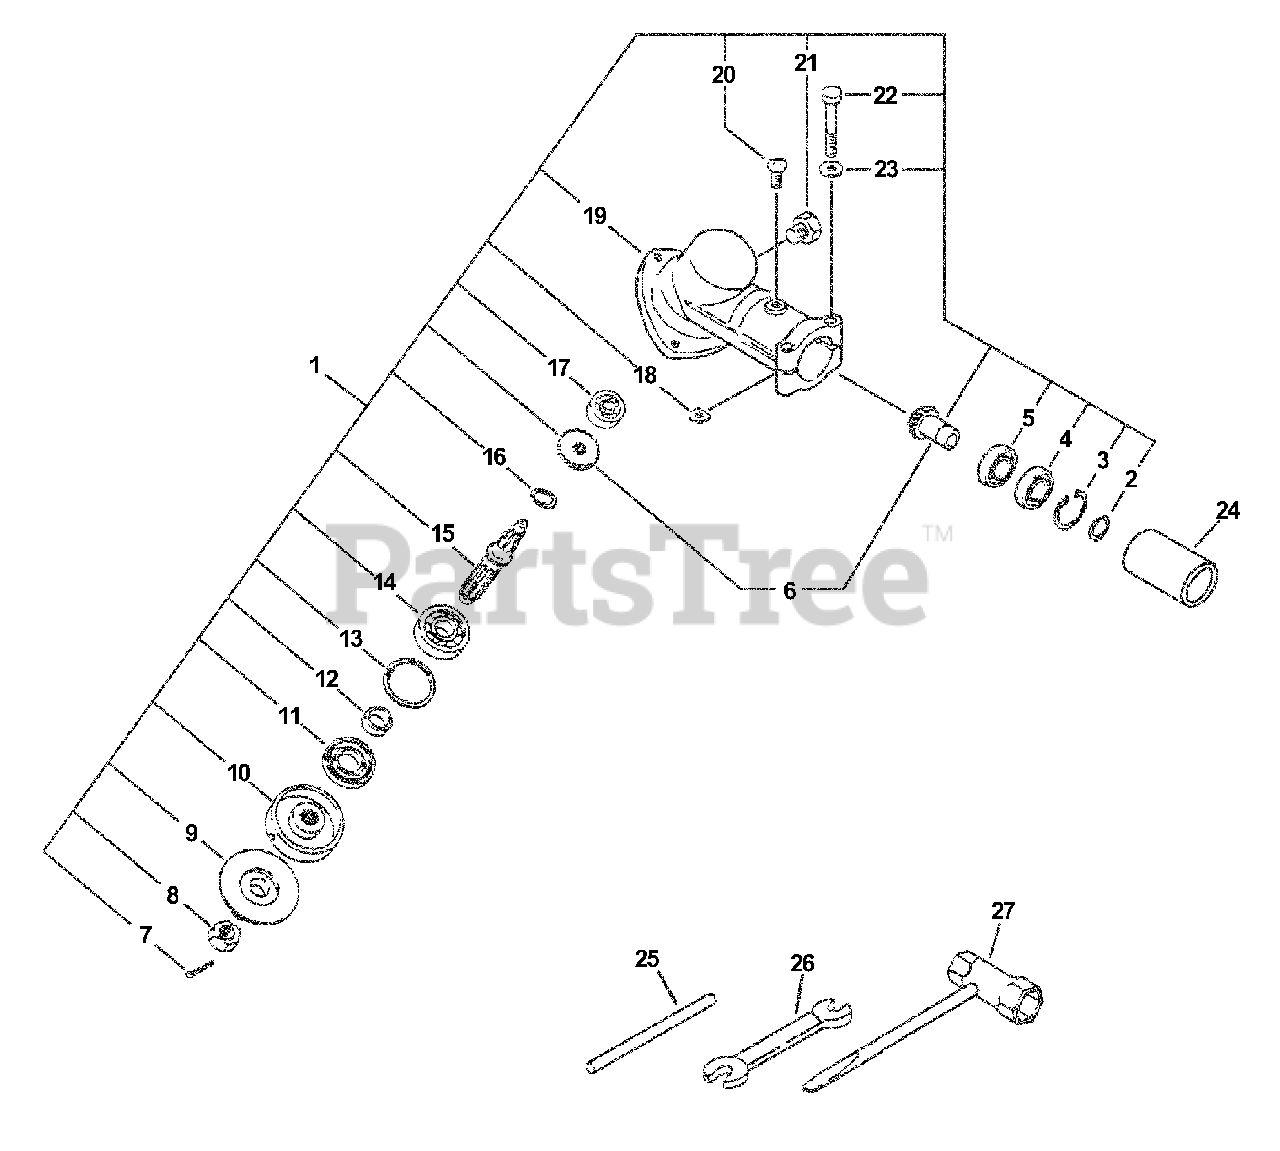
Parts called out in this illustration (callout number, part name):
1	GEAR CASE ASSY
2	RING, RETAINING - 10
3	RING, RETAINING - 22
4	BEARING, BALL - 6900Z
5	BEARING, BALL - 6900
6	GEAR SET - BEVEL
7	PIN, SPLIT - 2X22
8	LOCKNUT - LEFT HAND
9	ADAPTOR, BLADE - LOWER
10	ADAPTOR, BLADE - UPPER
11	SEAL, OIL
13	RING, RETAINING - 32
14	BEARING, BALL - 6201
15	GEAR - SHAFT
16	RING, RETAINING - 12
17	BEARING, BALL - 609
19	CASE, GEAR
20	SCREW - 5X14
21	BOLT - 8X8
22	BOLT - 5X30
23	WASHER - 5
25	LOCKING TOOL
26	SPANNER - 8X10mm
27	T-WRENCH - 17X19mm
